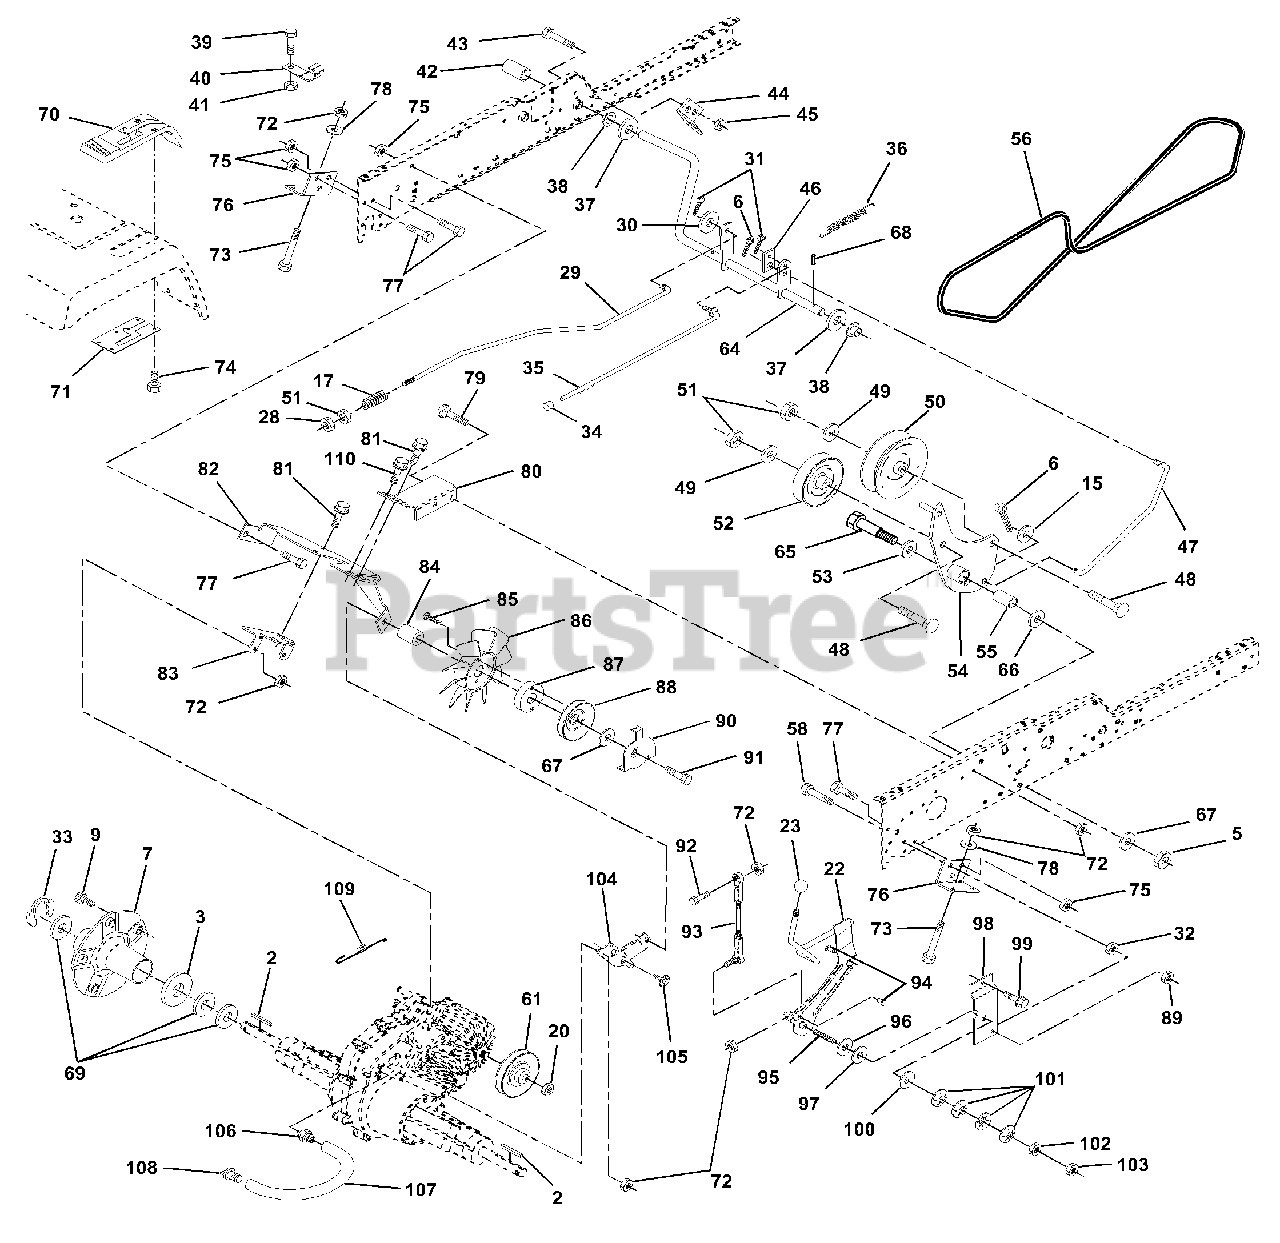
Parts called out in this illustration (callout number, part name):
2	Key 1/4 x 2.5
3	Washer Thrust Axle Harden
5	Nut Crownlock 3/8-16
6	Pin Cotter 1/8 x 3/4
7	Wheel Hub Asm.
15	Washer 13/32 x 13/16 x 16 Ga.
17	Spring Rod Brake
20	Nut Hex Jam Toplock 1/2-20
22	Shaft Arm Asm
28	Nut, Hex Jam 3/8-16
30	Washer 13/32 x 1 x 14Ga
31	Pin Cotter 3/32 x 3/4
32	Nut Hex 7/16-14
34	Cap Plunger
35	Rod Parking Brake
36	Spring Extension
37	Washer 25/32 x 1-1/4 x 16 Ga.
39	Screw Fin #10-24 x 1
40	Actuator Interlock Switch
41	Nut Lock #10-24
42	Cover Pedal
43	Bolt Hex Head 1/4-20 x 3/4
44	Bracket Interlock
45	Nut Lock W/Insert 1/4-20
46	Retainer Spring
47	Clutch Rod
48	Bolt Carriage 3/8-16 x 1-3/4 Gr. 5
49	Washer 13/32 x 7/8 x 13 Ga
50	Pulley Idler Flat
51	Nut Lock Hex 3/8-16
52	Pulley Idler Grooved
53	Washer Hartdened
54	Clutch Arm Asm
55	Bearing, Idler
58	Bolt Fin Hex 7/16-14 x 1-1/2
61	Pullery Transaxle
64	Shaft Asm Brake Parking Clutch
65	Bolt Shoulder
66	Washer Hardened
67	Washer 13/32 x 13/16 x 12 Ga
70	Console Hydro Fender
71	Plate Console Shift
72	Locknut Hex W/Washer Insert
73	Bolt Fin Hex 5/16-18 x 3
74	Screw, Hex Wsh Hi-Lo 1/4-1/2
75	Nut Lock Hex 7/16
76	Bracket Transaxle
77	Bolt Fin Hex 7/16-14 x 1
78	Washer 11/32 x 3/4 x 12 Ga.
79	Bolt Carriage 5/16-18 x 5/8
80	Bracket Torque RH
81	Screw Thdrol 3/8-16 x 3/4
82	Bracket Mount Torque/Fan
83	Strap Torque Mid
85	Screw #10-24 x 1-1/4
86	Fan 7" Hydro
87	Adapter Fan
88	Pulley Idler
89	Nut, Crownlock 7/16-14
90	Keeper Belt
91	Screw Thdrol 3/8-16 x 2-3/4
92	Bolt Fin Hex 5/16-18 x 1.75
93	Link Shift Asm
94	Fastner Christmas Tree
95	Screw Set 5/16-18 x 1.75
96	Washer Nickel Plated
97	Bearing Trust
98	Bracket Shift
99	Screw Thdrol 3/8-16 x 1-1/2
100	Washer Compression
101	Washer Bellville
102	Nut Hex Nylok
103	Nut Hex Jam 5/16-18
104	Bracket Idler
105	Screw Tap 1/4-20 x 1/2
106	Fitting Vent Hose
109	Spring Return Brake
110	Screw, Hinge
